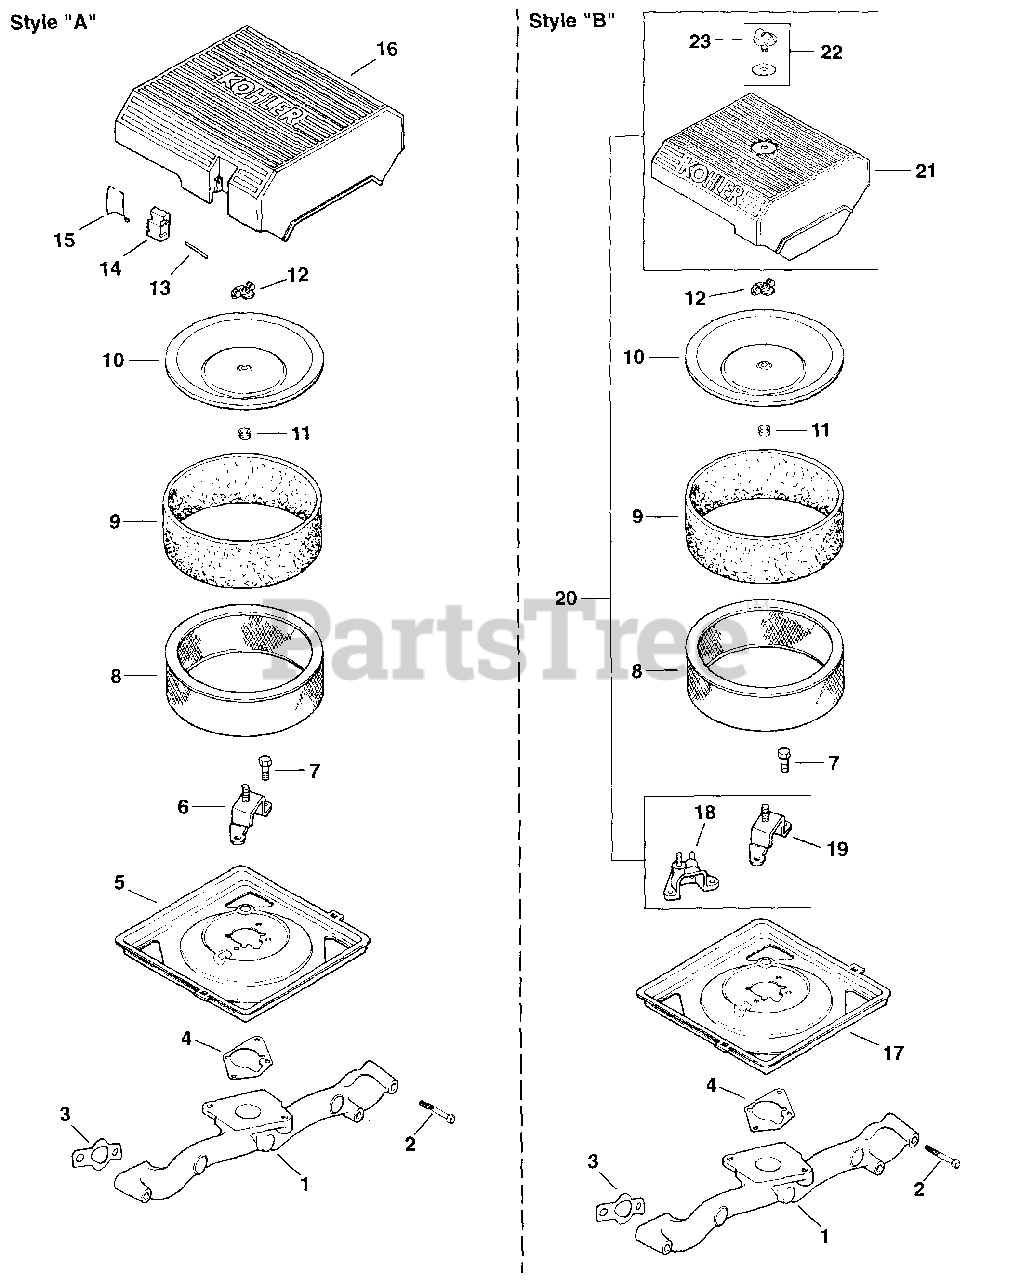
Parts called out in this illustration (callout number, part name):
1	MANIFOLD, METAL INTAKE
2	Screw, hex. flange M6x1.0x55
3	GASKET, INTAKE MANIFOLD USE 24 041 79-S
4	GASKET, AIR CLEANER BASE
7	SCREW - USE M-639016
8	ELEMENT, AIR CLEANER - Also available Retail Packaged 47 883 03-S1 Air Filter Kit
9	ELEMENT, PRECLEANER (LOW)
10	COVER, INNER AIR CLEANER
11	SEAL, INNER AIR CLEANER
12	NUT, WING
18	KIT - USE 24 755 86
19	BRACKET,AIR CLEANERBASE-USE 24 126 206-S
20	KIT, AIR CLEANER COVER
22	KIT - USE 54 755 01
23	KNOB - USE 25 341 03
